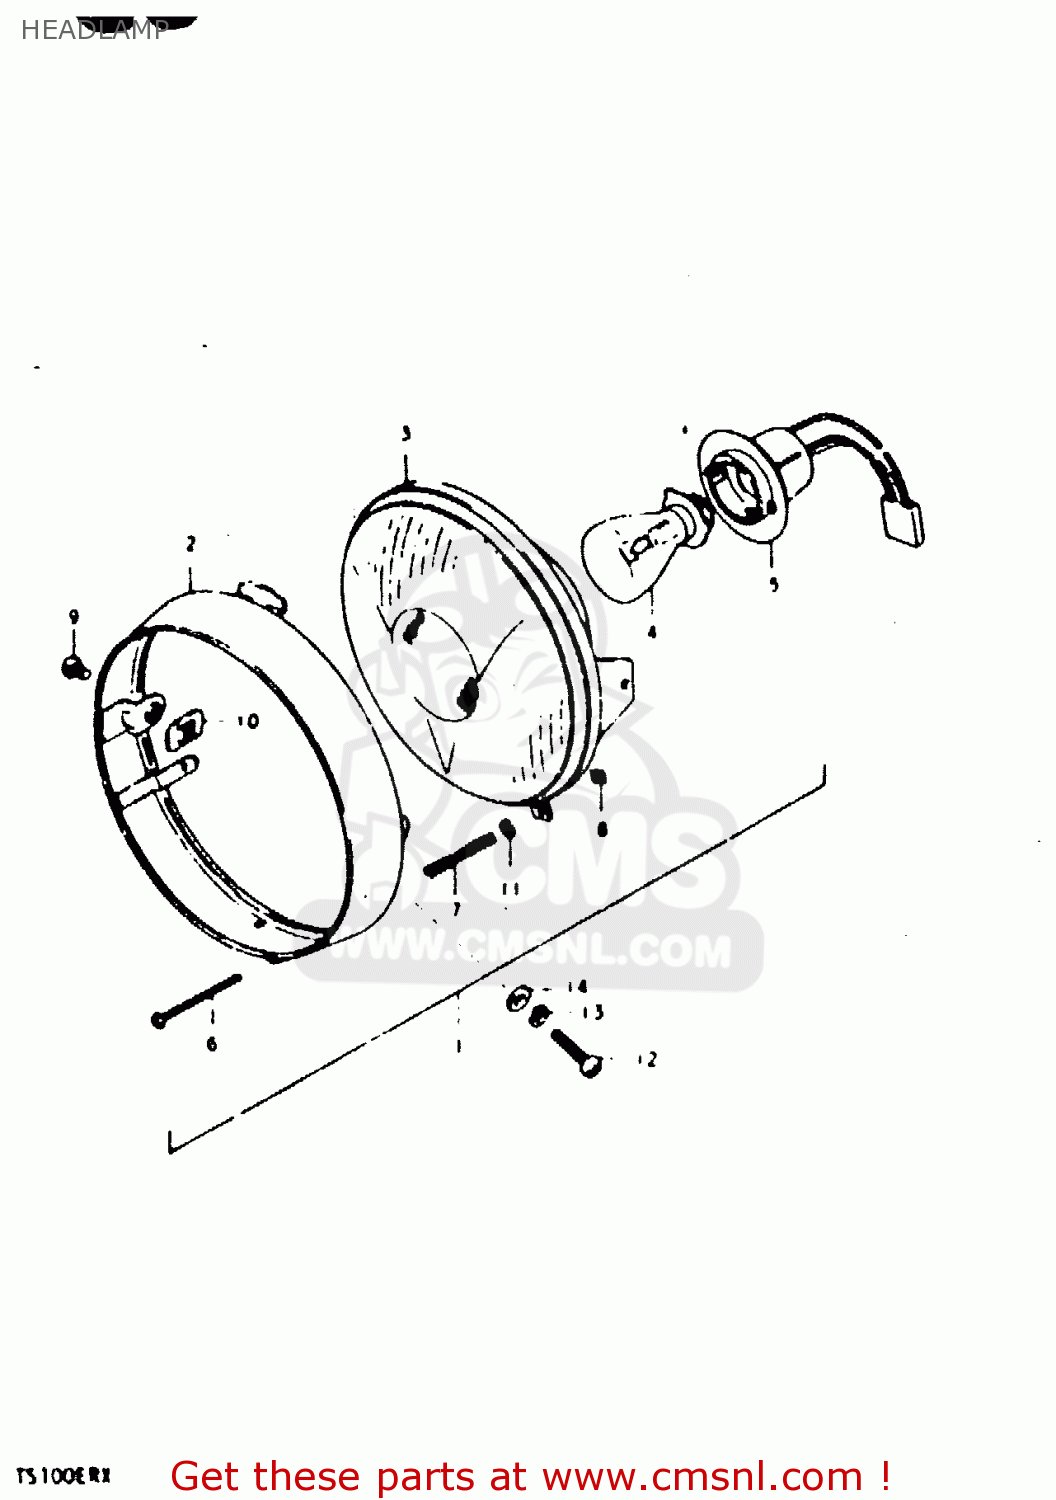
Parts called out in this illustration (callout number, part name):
1	HEADLAMP ASSY
2	RIM
3	LAMP UNIT
4	BULB(6V25/25W,STANLEY,A7007)
5	SOCKET,HEADLAMP
6	SCREW,HEADLAMP ADJUST
7	SPRING
8	NUT,HEADLAMP ADJUSTER
9	SCREW
10	NUT
11	WASHER
12	SCREW
13	LOCK WASHER
14	WASHER
